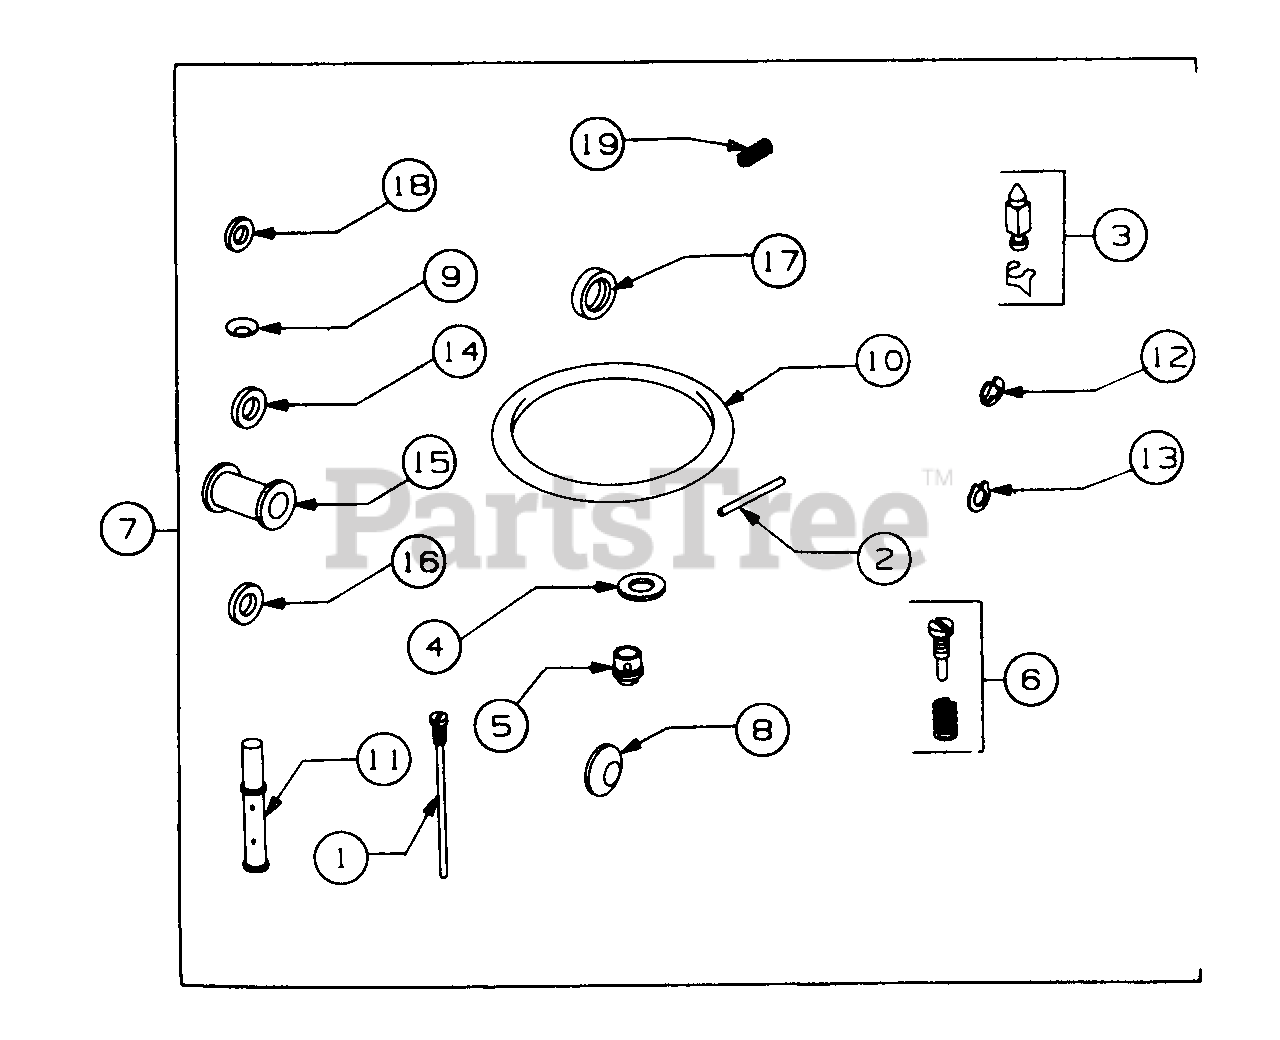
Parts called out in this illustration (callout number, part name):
1	Nozzle, Carburetor
2	Pin, Float Hinge
3	Valve, Fuel Inlet
4	Gasket, Sealing
5	Jet, Main
6	Valve Assy, Carburetor Idle
7	Overhaul Kit, Carburetor
8	Plug, Welch
9	Plug, Welch
10	Gasket, Bowl Mtg (Sold in kit only)
11	Nozzle
12	Retainer, Choke Shaft
13	Retainer, Throttle Shaft
14	Collar, Throttle
15	Collar, Throttle
16	Collar, Choke
17	Seal, Throttle Shaft
18	Seal, Choke Shaft
19	Ball, Choke Locator
